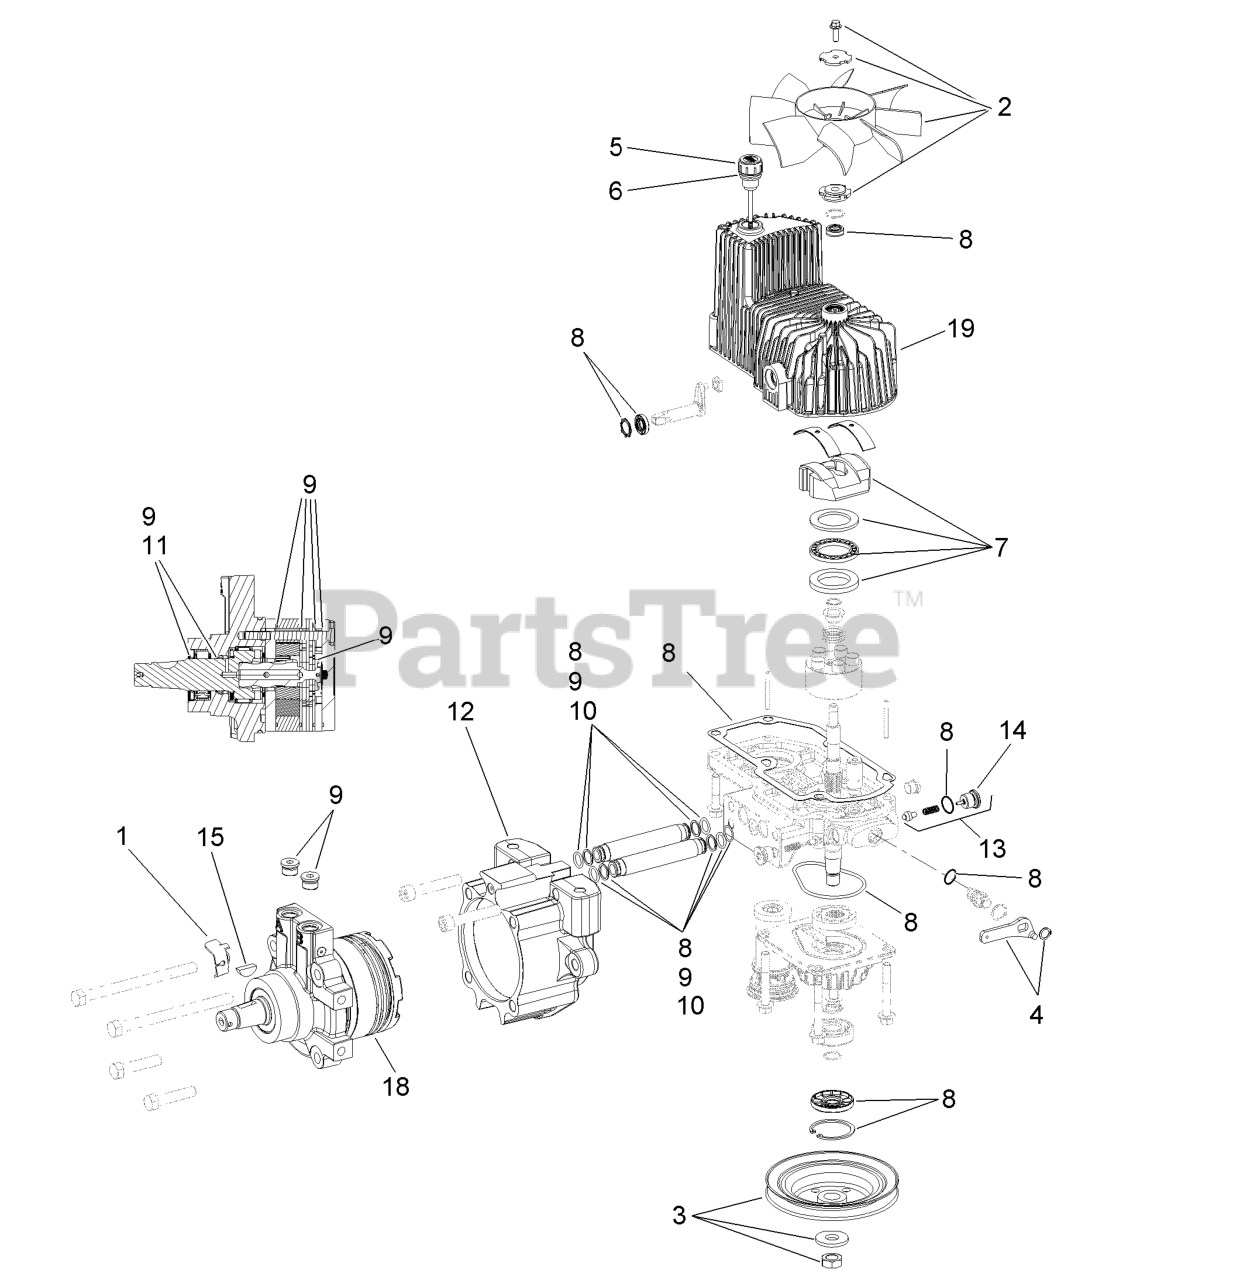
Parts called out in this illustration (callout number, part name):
1	BRACKET-ANCHOR, CABLE
2	FAN KIT
3	PULLEY KIT
4	HANDLE-BYPASS VALVE, HYDRO
5	DIPSTICK-HYDRO W/GASKET
6	GASKET-DIPSTICK, HYDRO
7	SWASH BLOCK KIT
8	PUMP SEAL KIT
9	MOTOR SEAL KIT
10	TUBE SEAL KIT
11	OUTPUT SHAFT SEAL KIT
13	CHECK VALVE ASM
14	PLUG-CHECK (W/O-RING)
15	KEY-WOODRUFF
19	HOUSING-HYDRO, RH
